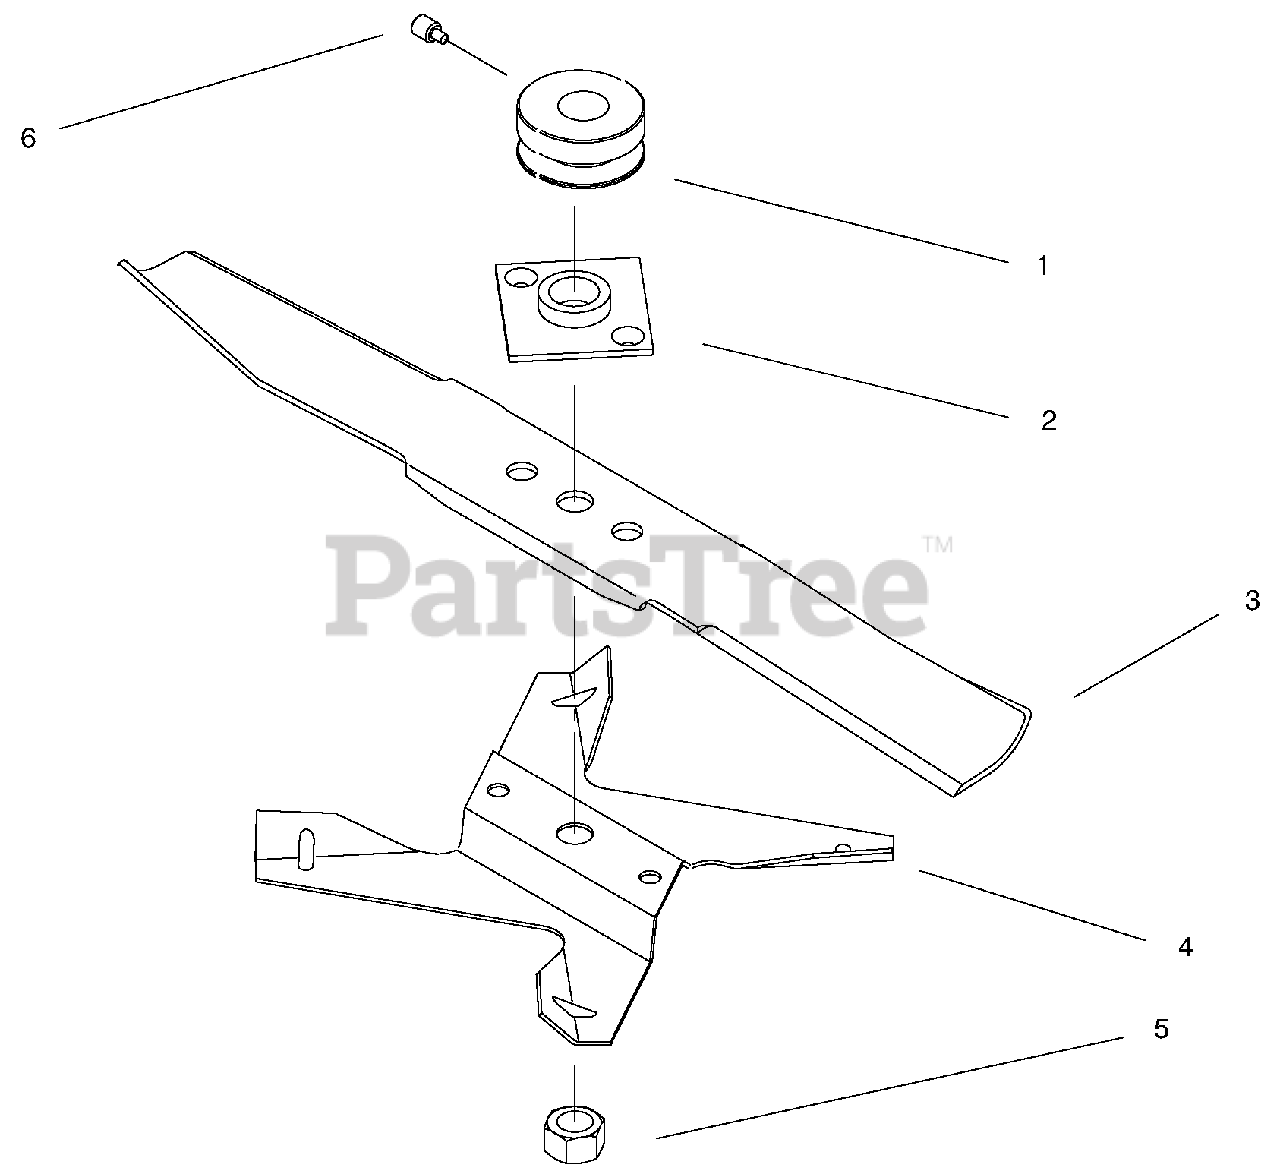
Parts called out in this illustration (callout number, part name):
1	Pulley-Engine
2	Plate & Collar
3	Blade-21"
4	Fan-Mulching
5	Nut-Blade
6	Screw-Set
